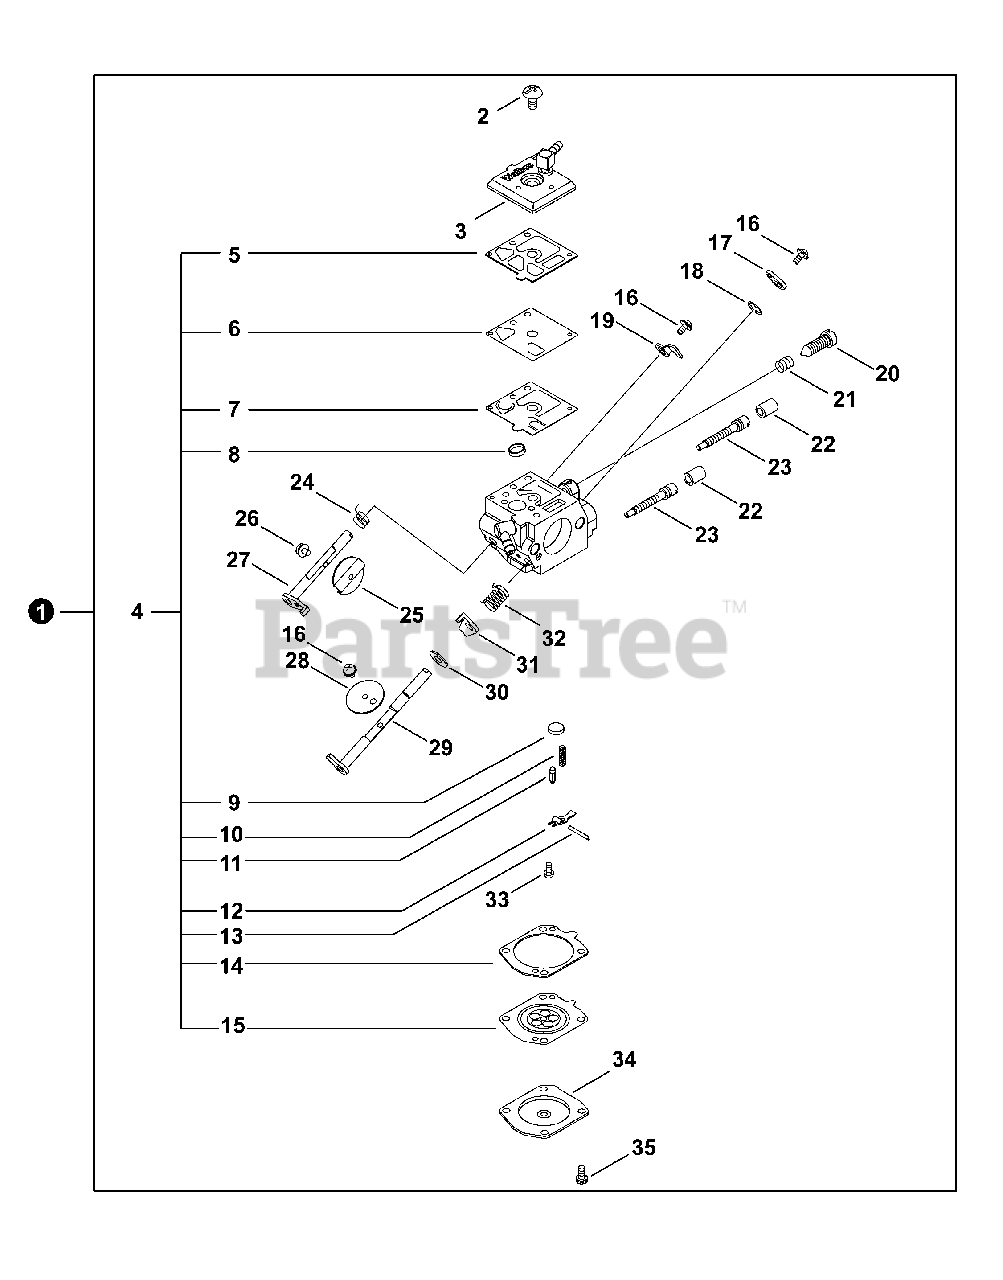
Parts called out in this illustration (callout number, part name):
1	CARBURETOR
3	COVER, FUEL PUMP
4	REPAIR KIT, CARBURETOR
5	GASKET, FUEL PUMP
6	DIAPHRAGM, PUMP
7	DIAPHRAGM, FUEL PUMP
8	SCREEN, FUEL INLET
9	PLUG, WELCH
10	SPRING, METERING LEVER
11	VALVE, INLET NEEDLE
12	LEVER, METERING
13	PIN, METERING LEVER
14	GASKET, METERING DIAPHRAGM
15	DIAPHRAGM, METERING
17	LEVER, THROTTLE
19	STOP, THROTTLE
20	SCREW, IDLE ADJUST
21	SPRING, IDLE ADJUST
22	CAP, LIMITER
23	NEEDLE, MIXTURE
24	SPRING, THROTTLE RETURN
25	VALVE, THROTTLE
27	SHAFT ASSY, THROTTLE
28	VALVE, CHOKE
29	SHAFT ASSY, CHOKE
31	LEVER, FAST IDLE
32	SPRING, CHOKE RETURN
34	COVER, DIAPHRAGM
